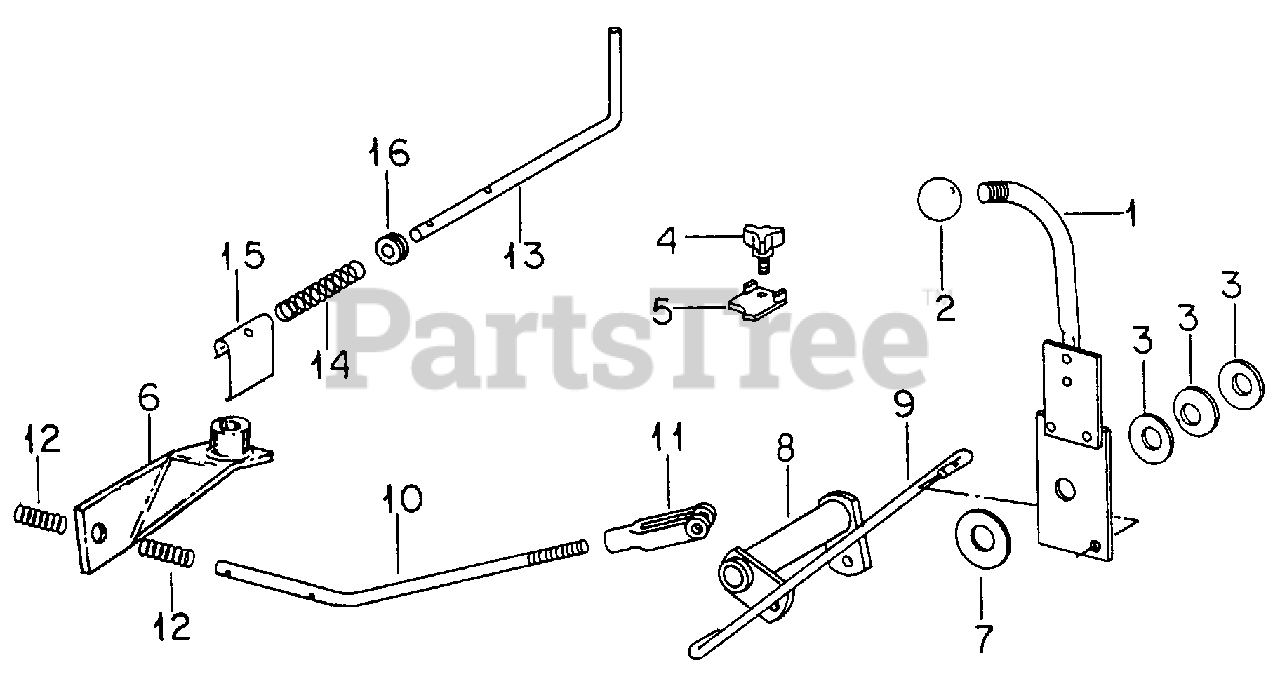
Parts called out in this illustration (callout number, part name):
1	Lever Assy, Speed Control
2	Knob, Shifter
3	Spring, Belleville
4	Knob, Fluted
5	Stop, Handle Detent
6	Arm Assy, Control Shaft
7	Washer, Frictional Disc
8	Rockshaft Assy
9	Rod, Control
10	Rod, Control Rear
11	Clevis, 5/16-24 Adj Rod End
12	Spring, Compression
13	Rod, Dump Valve
14	Spring, Dump Valve
15	Lever, Dump
16	Grommet, Rubber
